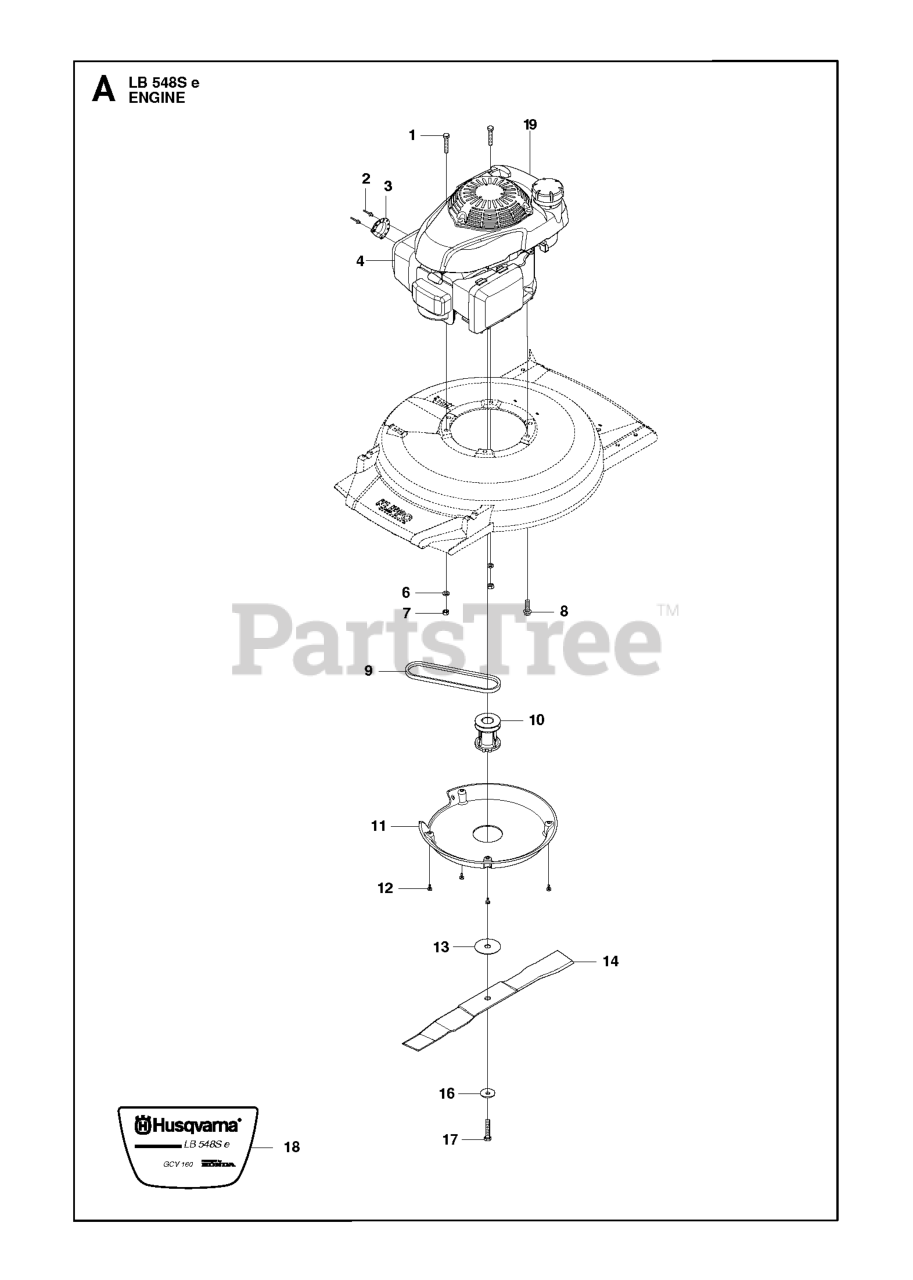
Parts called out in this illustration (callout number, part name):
2	Rivet
6	WASHER BRB 8.4X17
7	LOCKNUT M8
12	SCREW ITXPANTT M5X10 ZPB (A00
